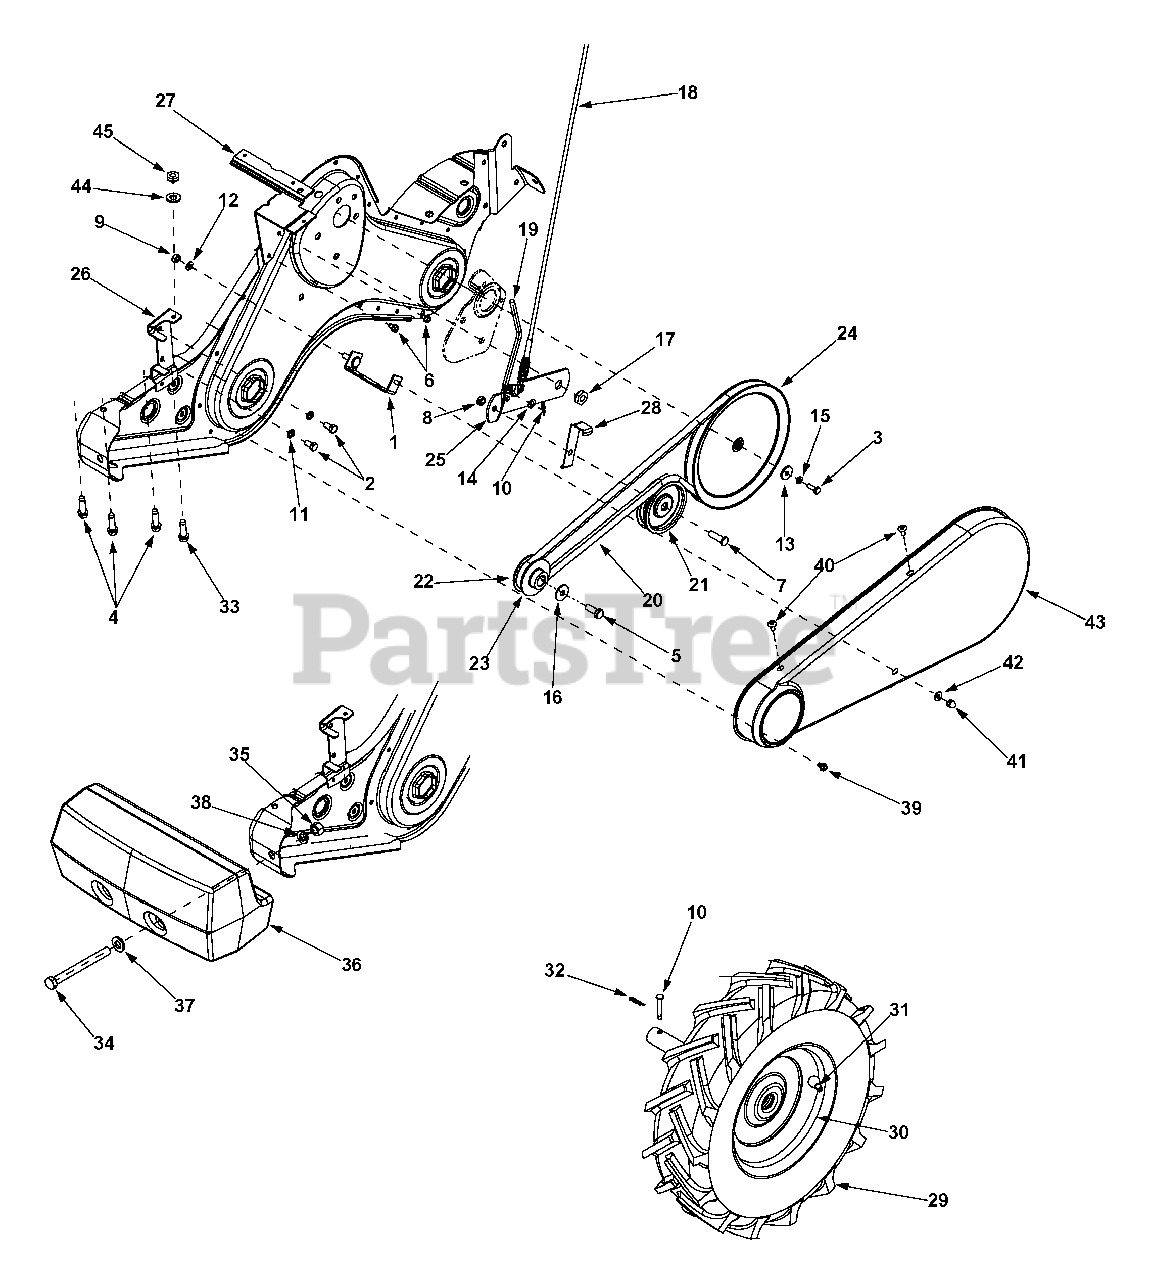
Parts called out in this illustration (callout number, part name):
2	Hex Bolt 5/16-24 x.62"
3	Hex Bolt 1/4-28 x.75"
4	Hex Washer Screw 3/8-16 x 1.25"
5	Hex Bolt 3/8-24 x 1.0
6	Hex Washer Screw
7	Hex Cap Screw 3/8-16 x 1.25
8	Lock Jam Nut 3/8-16
9	Hex Nut 5/16-18
10	Internal Cotter Pin
11	Lock Washer 5/16
12	Lock Washer 5/16"
13	Flat Washer.25 ID x.93 OD
14	Spring Washer.317 ID x.625 OD
15	Lock Washer 1/4" ID
16	Bell Washer.396 ID x 1.14 OD
17	Shoulder Nut 7/16-20
18	Clutch Cable
19	Idler Pulley Rod
20	V-Belt 4L x 58.16 Lg
21	Flat Idler w/Flange 3.75 OD
22	Engine Inner Pulley Half
23	Engine Outer Pulley Half
24	Input Pulley
25	Idler Pulley Bracket
26	Belt Keeper Bracket
29	Wheel Assembly RH 16 x 4 x 8
32	Clevis Pin
33	Hex Bolt 5/16-18 x 1.50
34	Hex Bolt 1/2-13 x 5.0
35	Hex Nut 1/2-13
36	Counterweight
37	Flat Washer.50 ID x 1.25 OD
38	Lock Washer 1/2
39	Hex Screw 1/4-20 x.375
40	Screw 1/4-14 x.625
41	Lock Nut
42	Flat Washer.271 ID x.630 OD
44	Bell Washer.340 ID x.872 OD
45	Hex Nut 5/16-18
